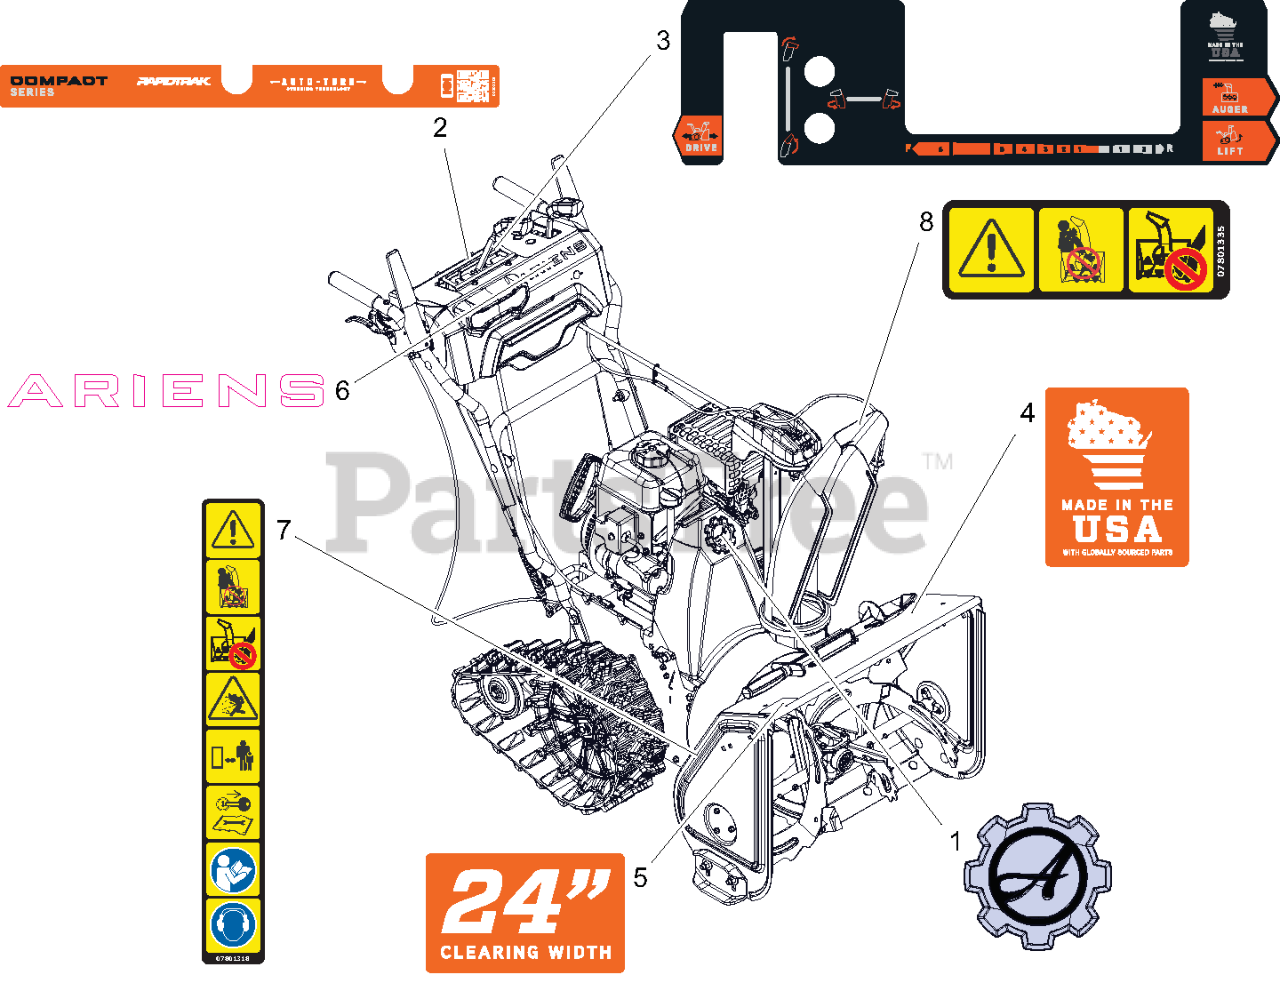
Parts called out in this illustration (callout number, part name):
1	DECAL, ARIENS - GEAR BADGE
2	DECAL- DASH - COMPACT RT
3	DECAL, CONTROL - SMALL DASH TRACK
4	DECAL- MADE IN USA
5	DECAL- CLEARING - 24
6	DECAL- ARIENS - 7.46"
7	DECAL- SAFETY - DANGER
8	DECAL- DANGER
